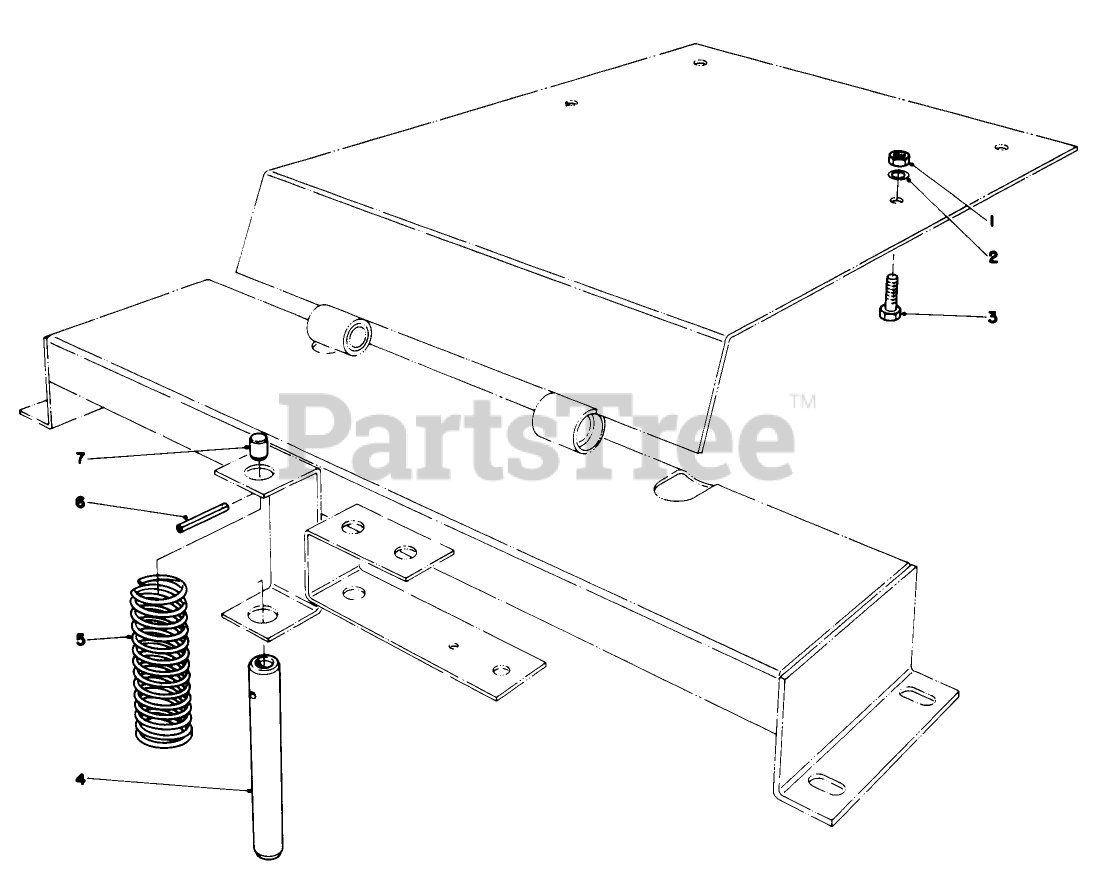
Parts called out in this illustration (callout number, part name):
1	NUT-HEX
2	WASHER-LOCK/SP
3	SCREW-HH
4	PIN-SWITCH, SEAT
6	PIN-ROLL, SLOTTED
7	PIN-PEDAL
